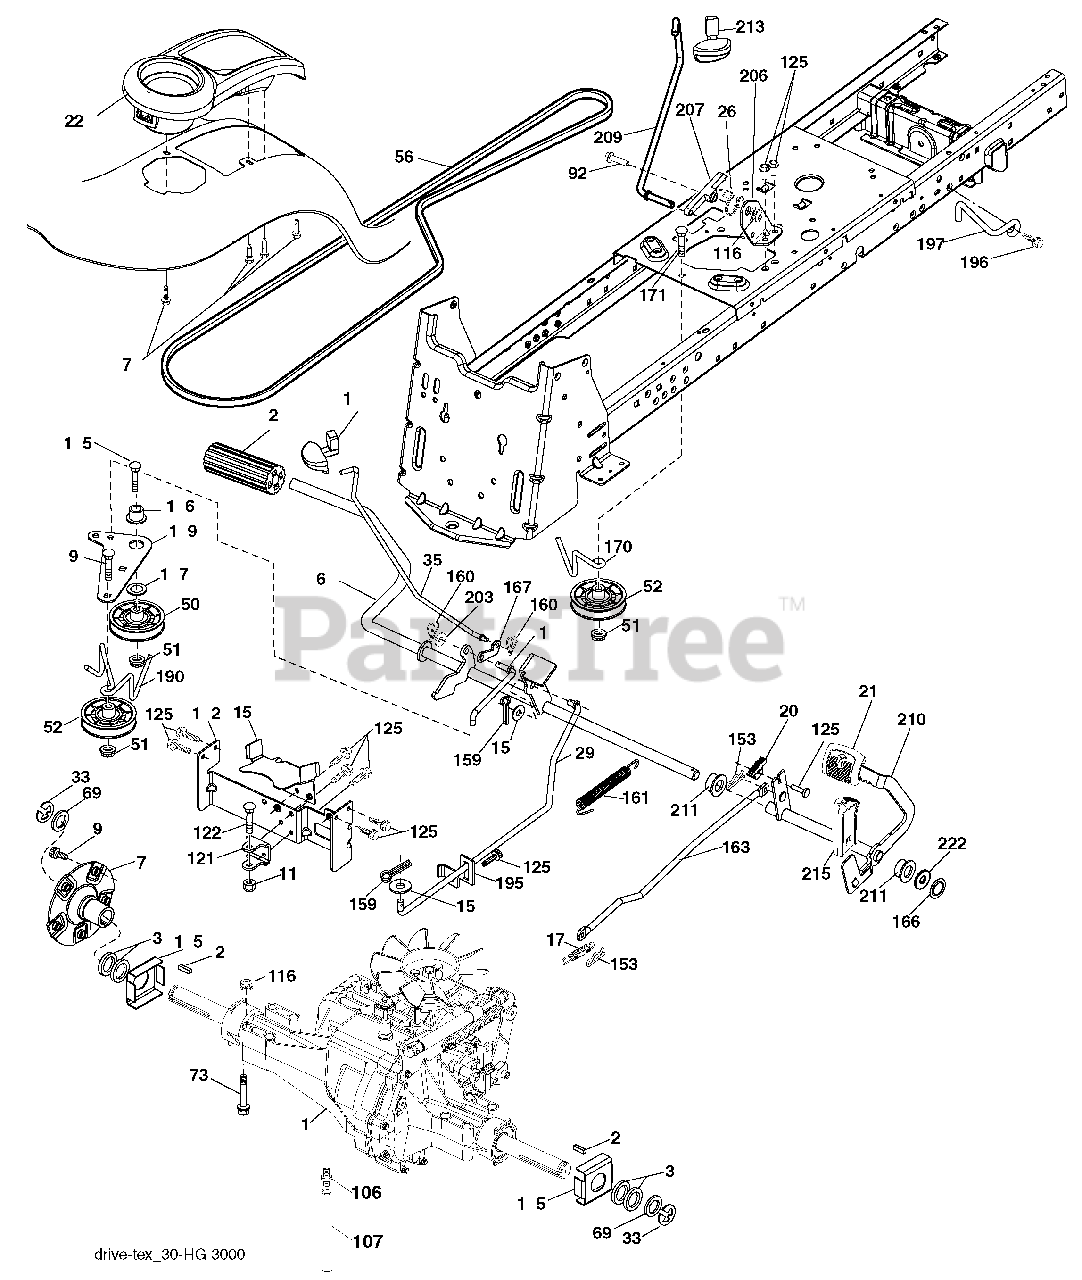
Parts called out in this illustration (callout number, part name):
2	Key 1/4 x 2.5
3	Washer Thrust Axle Harden
7	Hub Asm. Wheel
9	Bolt Hub Wheel
15	Washer 13/32 x 13/16 x 16 Ga.
17	Spring, Brake
26	Spring Return Cruise
29	Rod, Brake
33	Ring E #5133-100
35	Rod, Brake, Park
42	Cover, Foot Pedal
49	Bolt
50	Pulley Idler Flat
51	Lock Nut 3/8-16
52	Idler V-Groove 910" Offset
56	V-Belt, Drive
64	Shaft Asm. Pedal Brake Control
69	Washer 1-1/32 x 1-5/8 x 16 GA
73	Bolt 5/16 - 18 x 3.0. G5
74	Screw 1/4 x 1/2
92	Bolt Fin Hex 5/16-18 unc x 1.25
106	Cap Asm. Vent
107	Vent Tube
114	Nut Lock 5/16 x 18 UNC
116	Nut Lock Hex Flange 5/16-18
121	Bracker Strap Torque
122	Bolt 5/16 - 18 x 2.50
125	Screw 5/16-18 x 3/4
142	Strap Torque
145	Washer Axle Flange
153	Retainer Spring 1"
158	Keeper Belt T/A
159	Pin Cotter 1/8 x 3/4
160	Retainer Clip
161	Spring, Return, Clutch
163	Rod Control Pedal
166	Nut Push .625
167	Latch Brake Parking
170	Keeper Belt Centerspan
171	Bolt
184	Handle Parking Brake
185	Bolt
186	Spacer Retainer
187	Washer
188	Link Clutch Ground Drive
189	Bellcrank Ground Drive
190	Keeper Bellcrank Ground Drive
195	Retainer Rod Brake
196	Screw 3/8-16 x 1
197	Bracket Clutch Anti-Rotation
203	Washer 11/32 x 11/16 x 16 Ga.
206	Bracket Mount Latch Cruise
207	Latch Control Cruise
208	Gear Sector Control Cruise
209	Rod Control Cruise
210	Rocker Asm. Pedal Control
211	Bearing Nylon Blk .629
213	Knob Control Cruise
214	Pedal Forward
215	Pedal Reverse
222	Washer 21/32 x 1-1/4 x 10 Ga.
224	Console Toolbox
